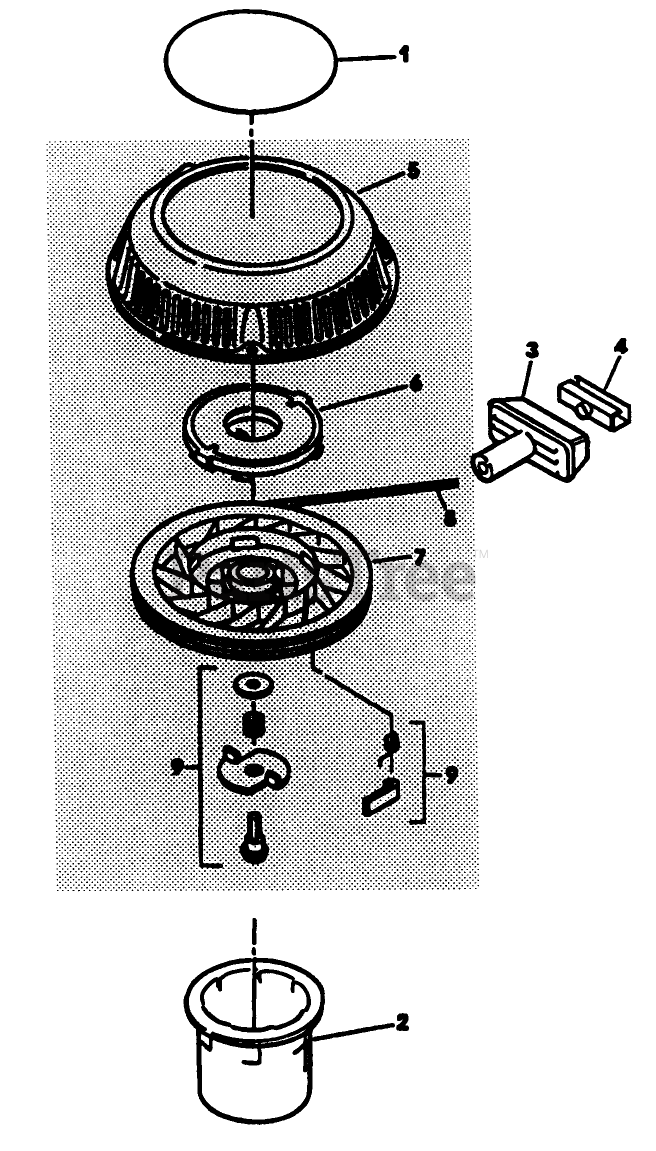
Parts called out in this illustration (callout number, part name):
2	HUB-STARTER E COMM.
4	CLIP-STARTER
5	STARTER HOUSING & SHAFT
7	PULLEY
9	DOG KIT
